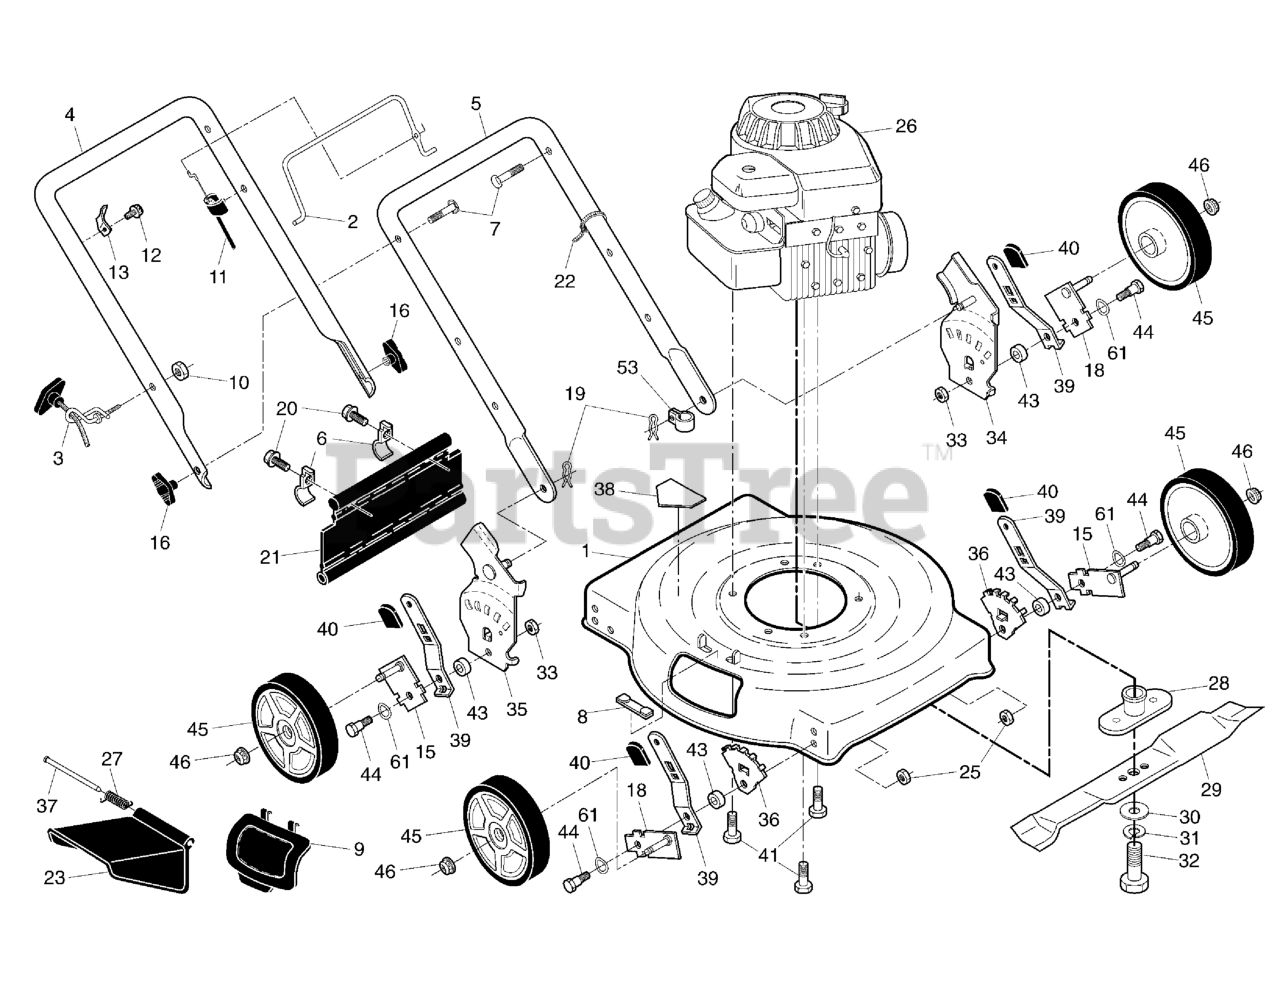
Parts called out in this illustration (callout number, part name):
1	Kit, Housing (Includes Key Number 38)
2	Control Bar
3	Rope Guide
4	Upper Handle
5	Lower Handle
6	Shoulder Bolt 5/16-18 x 1/2
7	Handle Bolt 5/16-18
8	Clip, Closeout
9	Mulcher Plate
10	Locknut, Hex 1/4-20
11	Engine Zone Control Cable
12	Screw, Hex Head, Threaded, Rolled, #10-16 x 5/8
13	Up-Stop Bracket
15	Axle Arm Assembly, Left Front & Right Rear
16	Handle Knob
18	Axle Arm Assembly, Right Front & Left Rear
19	Hairpin Cotter
20	Screw, Tapping, Hex Washer Head #10-24
21	Rear Defl ector
22	Wire Tie
23	Discharge Guard
25	Nut, Hex, Flangelock 5/16-18
26	* ENGINE, Briggs & Stratton
27	Torsion Spring
28	Blade Adapter
29	22" Blade
30	Hardened Washer
31	Helical Lockwasher 3/8
32	Screw, Hex Head, 3/8-24 x 1-3/8, G8
33	Nut, Hex, Flangelock 5/16-18
34	Wheel Bracket Support, LH
35	Wheel Bracket Support, RH
36	Wheel Bracket Adjuster
37	Hinge Rod
38	Danger Decal
39	Selector Spring
40	Selector Knob
41	Screw, Hex Head, Threaded, Rolled 3/8-16 x 1
43	Spacer
44	Shoulder Bolt 5/16-18 x .33
45	Wheel & Tire Assembly
46	Nut, Hex, Flangelock 3/8-16
53	Clip, Cable
61	Washer, Curved, Cylindrical
